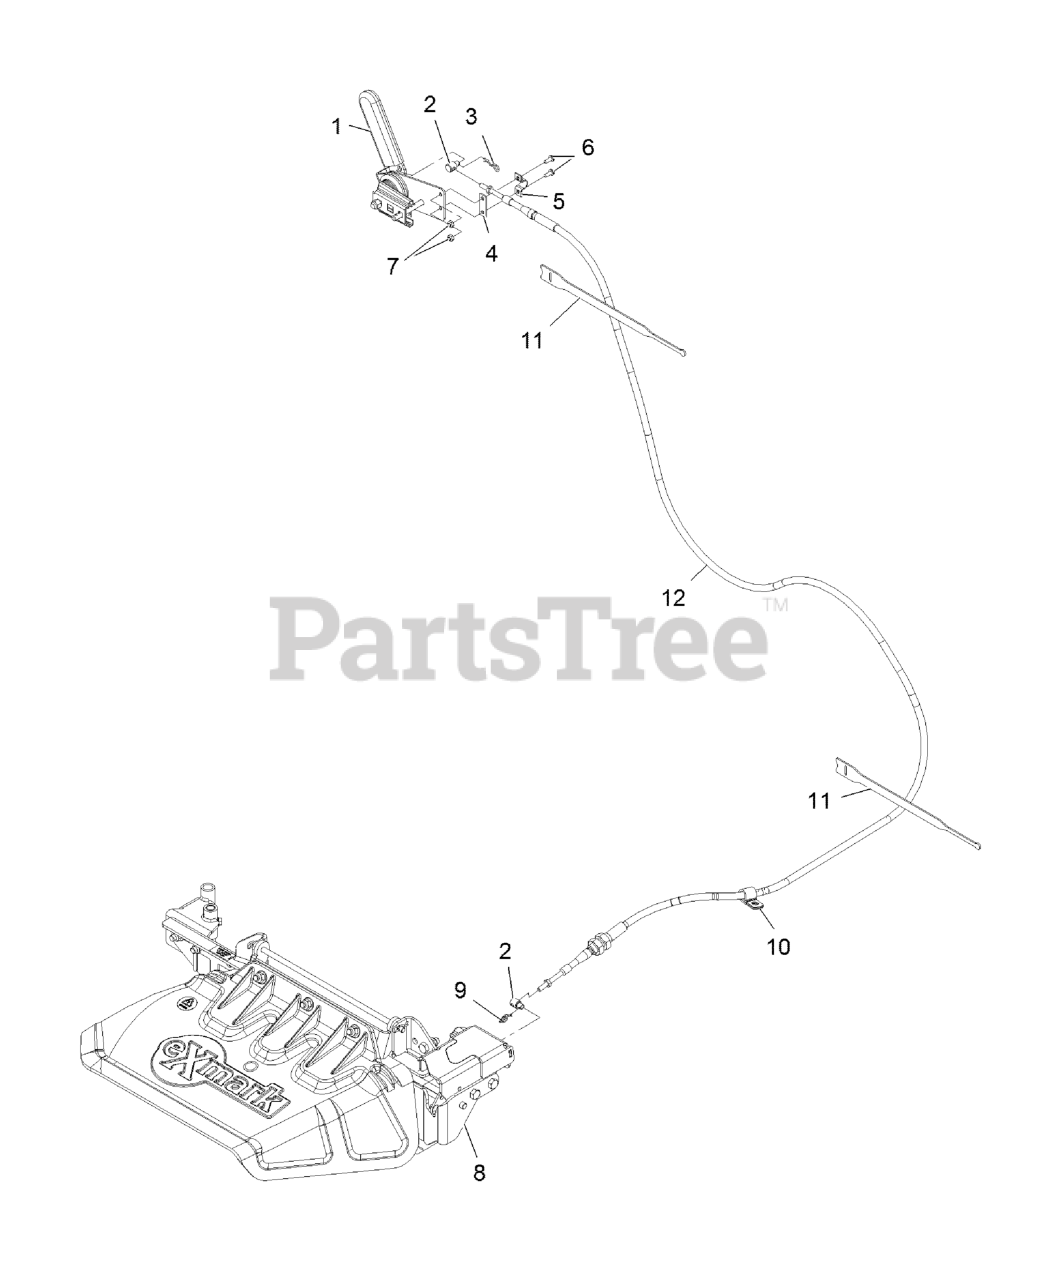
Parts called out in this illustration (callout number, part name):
1	ASM, HAND LEVER
2	PIVOT, CONTROL CABLE
3	PIN-COTTER
4	SHIM,CONTROL CABLE
6	SCREW-PPH
7	NUT-LOCK, NI
8	ASM, OCD
9	PIN-COTTER, LOCKING
10	CLIP-LOOM
11	STRAP-VELCRO, CABLE TIE
12	CABLE-DISCHARGE GATE
